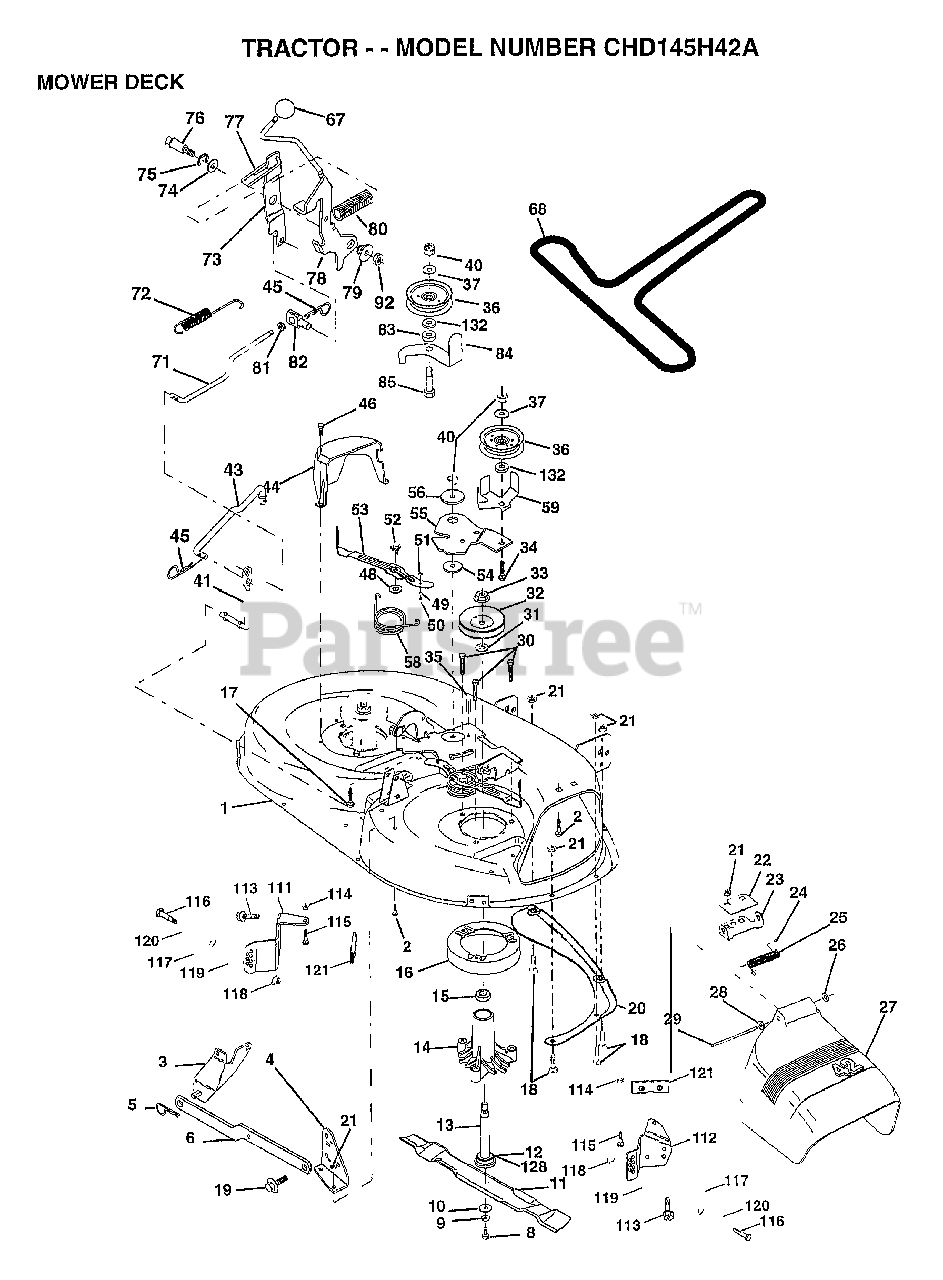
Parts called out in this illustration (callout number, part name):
1	DECK.WELD.42.
2	BOLT
3	BRKT ASM SWAY BAR
4	BRKT DECK SW BAR
8	BLADE BOLT
10	WASHER.HARD.BLADE
11	"BLADE.42"" HIPERF"
12	BEARING.BALL
14	HSG ASM MANDREL
15	BEARING
16	STRIPPER RND MWR
17	BOLT RDHD 3/8-16
18	BOLT
19	BOLT SHD 5/16-18
22	STIFFENER BRKT
23	DEFLECTOR BRKT
24	CAP-SLEEVE LT
25	SPRING TORSION
26	NUT PUSH M
27	DEFLECTOR.SHIELD
28	WASHER
29	HINGE ROD
31	WASHER
32	PULLEY.MANDREL.42
34	BOLT
35	XMAS TREE FASTNER
36	FLAT IDLER PULLEY
37	WASHER
41	PIVOT ROD
43	ROD CLUTCH W/NIBS
44	GUARD MAND LH BLK
45	RETAINER M
46	SCREW.1/4-20X5/8
48	HARD SMALL WASHER
49	ROLLER ASM-CAM
50	SHOULDER BOLT
51	LOCKNUT
52	BOLT.SHLD.5/16-18
54	HARDENED WASHER
55	ARM-IDLER
56	SPACER RETAINER
58	SPRING TORSN BRAK
59	GUARD IDLER TUV
67	KNOB T(3/8 HOLE)
68	BELT.V.T-PATH
71	ROD CLUTCH 38/42
72	RETURN SPRING
73	CLUTCH ARM SECOND
74	WASHER
75	RING
76	SHOULDER BOLT
77	SPRING KEEPER
78	LEVER ASM-CLUTCH
79	BUSHING
80	SPRING.CLUTCH.MWR
81	NUT
82	TRUNION ADJ
83	WASHER
84	"KEEPER-BELT,FIXED"
85	BOLT RDHD 3/8-16
92	NUT
111	BRACKET.GWHL.LH.
112	BRACKET.GWHL.RH.
113	SCREW
116	BOLT M
117	WHEEL.GAGE.BLK.PL
118	LOCKNUT
119	WASHER
120	WASHER
121	BRACKET.EXTRD.GWL
128	WASHER.FELT.
132	WASHER GT
